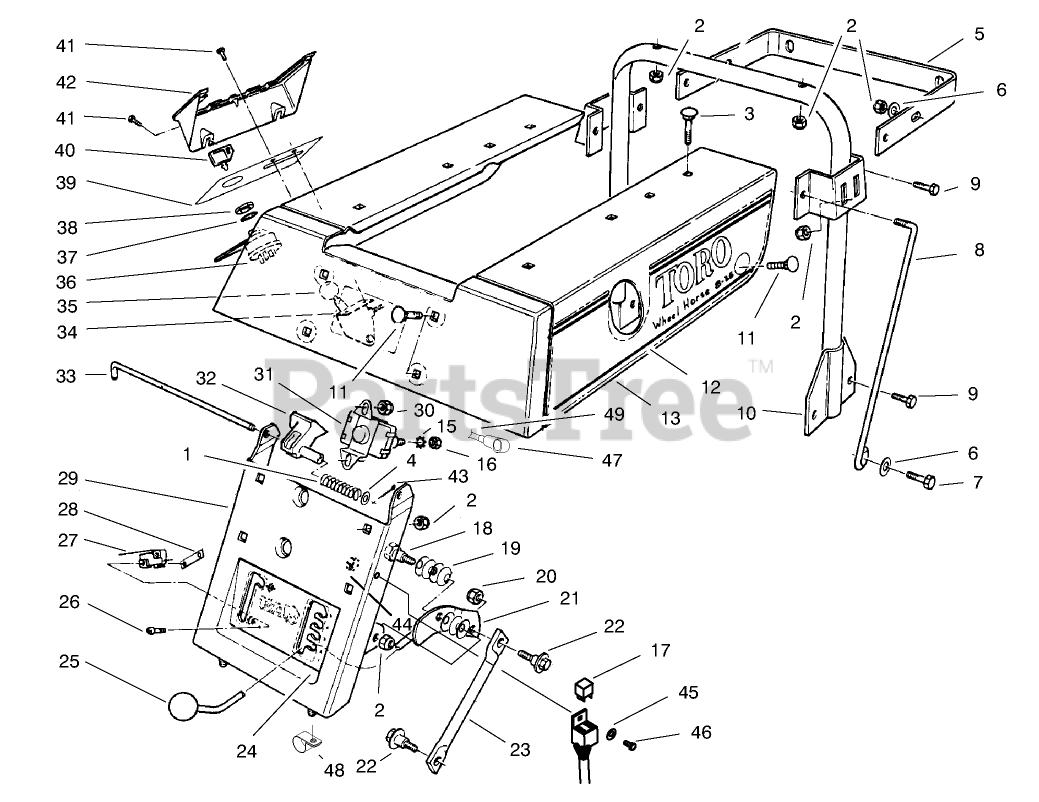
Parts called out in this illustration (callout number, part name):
1	SPRING-COMPRESSION
2	NUT-LOCK, NI
3	SCREW-CARR
4	WASHER-FLAT
5	STANDBAR
6	WASHER-PLAIN
7	SCREW-HH
8	BRACE-SEAT SUPPORT
9	SCREW-HH
10	SEAT SUPT ASM
11	BOLT-CARR
12	DECAL - RH SIDE PANEL
13	SEAT BODY WA
15	WASHER-LOCK
16	NUT-JAM
17	RELAY
18	BOLT-SHOULDER
19	WASHER-BELLEVILLE
20	NUT-LOCK, NI
21	HOC HDLE WA
22	BOLT-SHOULDER
23	LINK-HOC
25	KNOB-CONTROL
27	SWITCH-MICRO
28	NUT-SPEED
29	SEAT SUPPORT ASM
30	NUT-LOCK, NI
32	PROP-SEAT
33	ROD-SEAT BASE
34	CONTROL-THROTTLE
35	KNOB-CONTROL
37	WASHER-LOCK
38	NUT-HH
39	DECAL - CONTROL PANEL
40	KEY-IGNITION
41	SCREW-THD FORM, HWH
43	PIN-COTTER
44	NUT-LOCK, NI
45	WASHER-FLAT
47	BOOT-INSULATOR, TERMINAL
48	CLIP-FUEL LINE
49	ASM - CABLE
